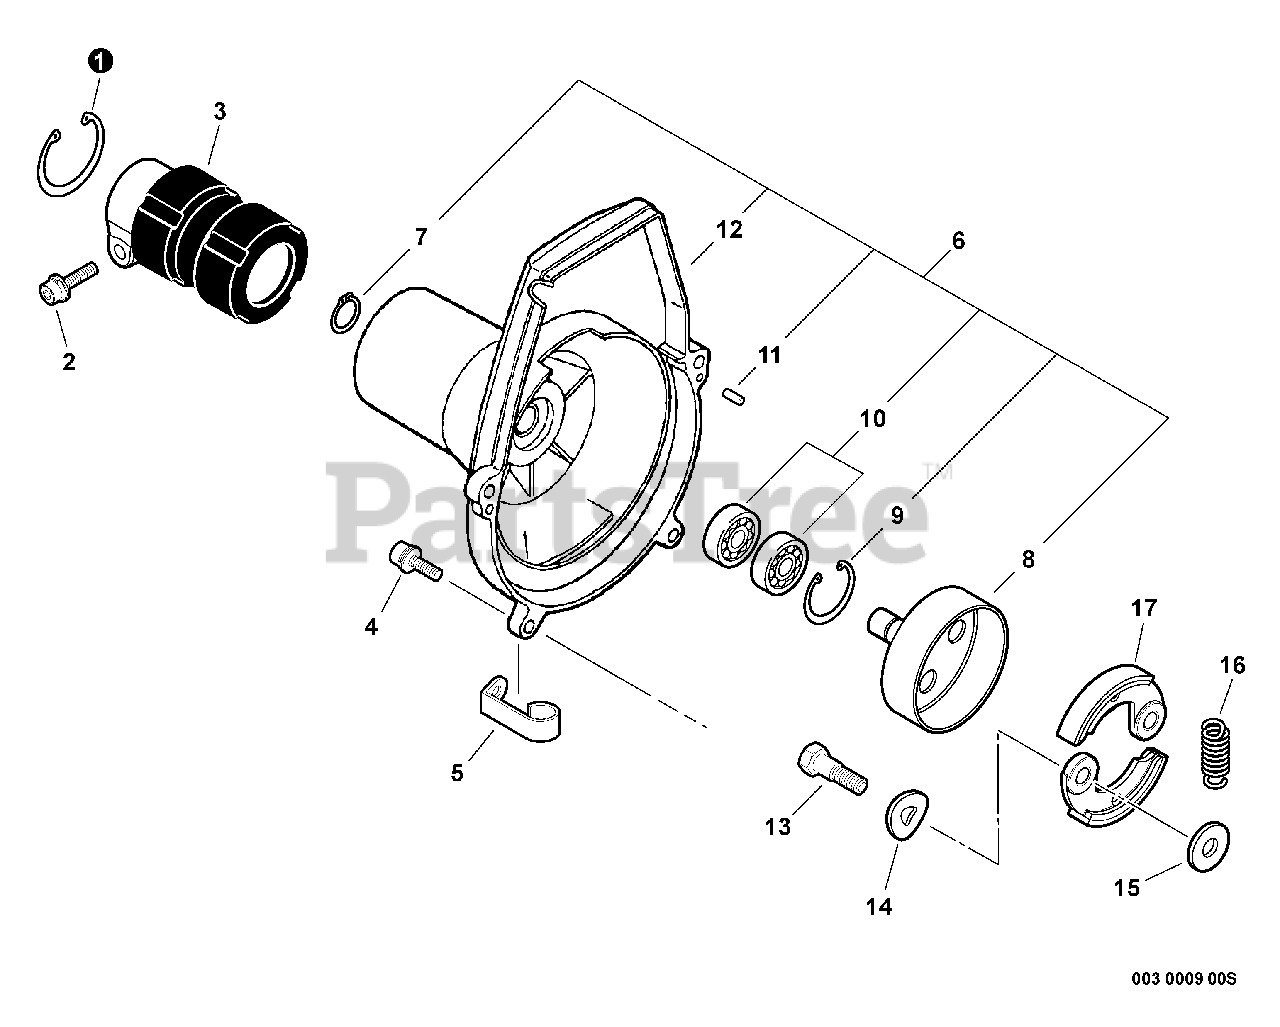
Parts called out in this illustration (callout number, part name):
1	RING, RETAINING - 42
2	SCREW - 5X28
3	CLAMP, MAIN PIPE
4	SCREW - 5X18
6	FAN CASE ASSY - GRAY
7	RING, RETAINING - 12
8	DRUM, CLUTCH
9	RING, RETAINING - 28
10	BEARING, BALL - 6001
11	PIN - LOCATING
12	CASE, FAN - GRAY
13	BOLT, CLUTCH
14	WASHER - SPRING
15	WASHER - 6
16	SPRING, CLUTCH
17	SHOE, CLUTCH
